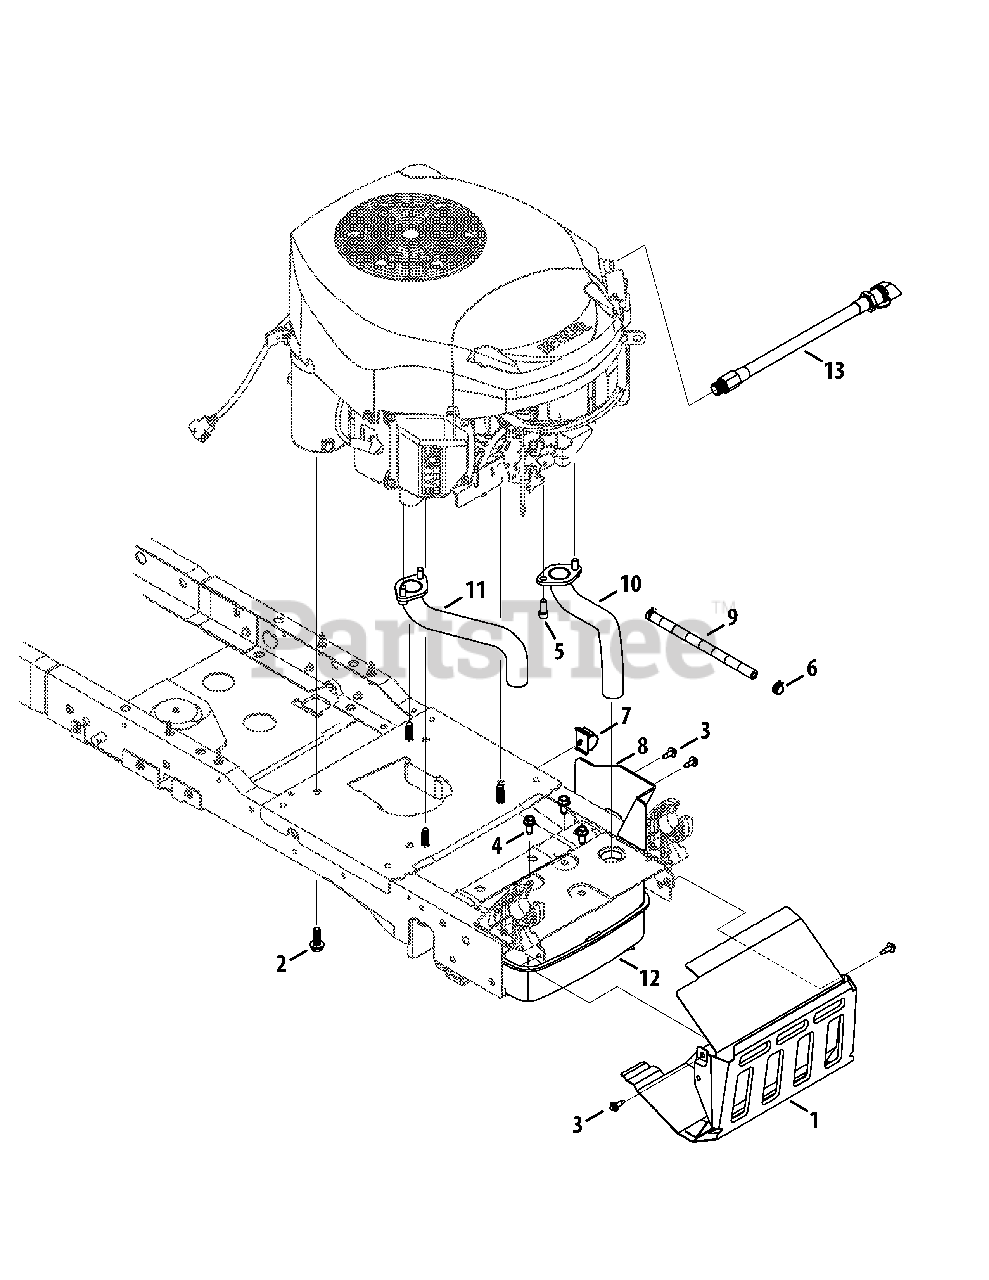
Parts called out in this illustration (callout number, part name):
1	Shield Ass’y, Muffler
2	Screw, Self-tapping, 3/8-16, 1.0
3	Screw, M6-1 x .625
4	Screw, Self-tapping, M8-1.25, .750
5	Screw, Sokt Head, 5/16-18, .750
6	Clamp, Hose, .490 Dia.
7	Push Mount Wire Clip, .750
8	Muffler Shield
9	Hose, Fuel, Low Permeation, 1/4
10	Exhaust Pipe, LH
11	Exhaust Pipe, RH
12	Muffler, Kohler
13	Drain, Oil
